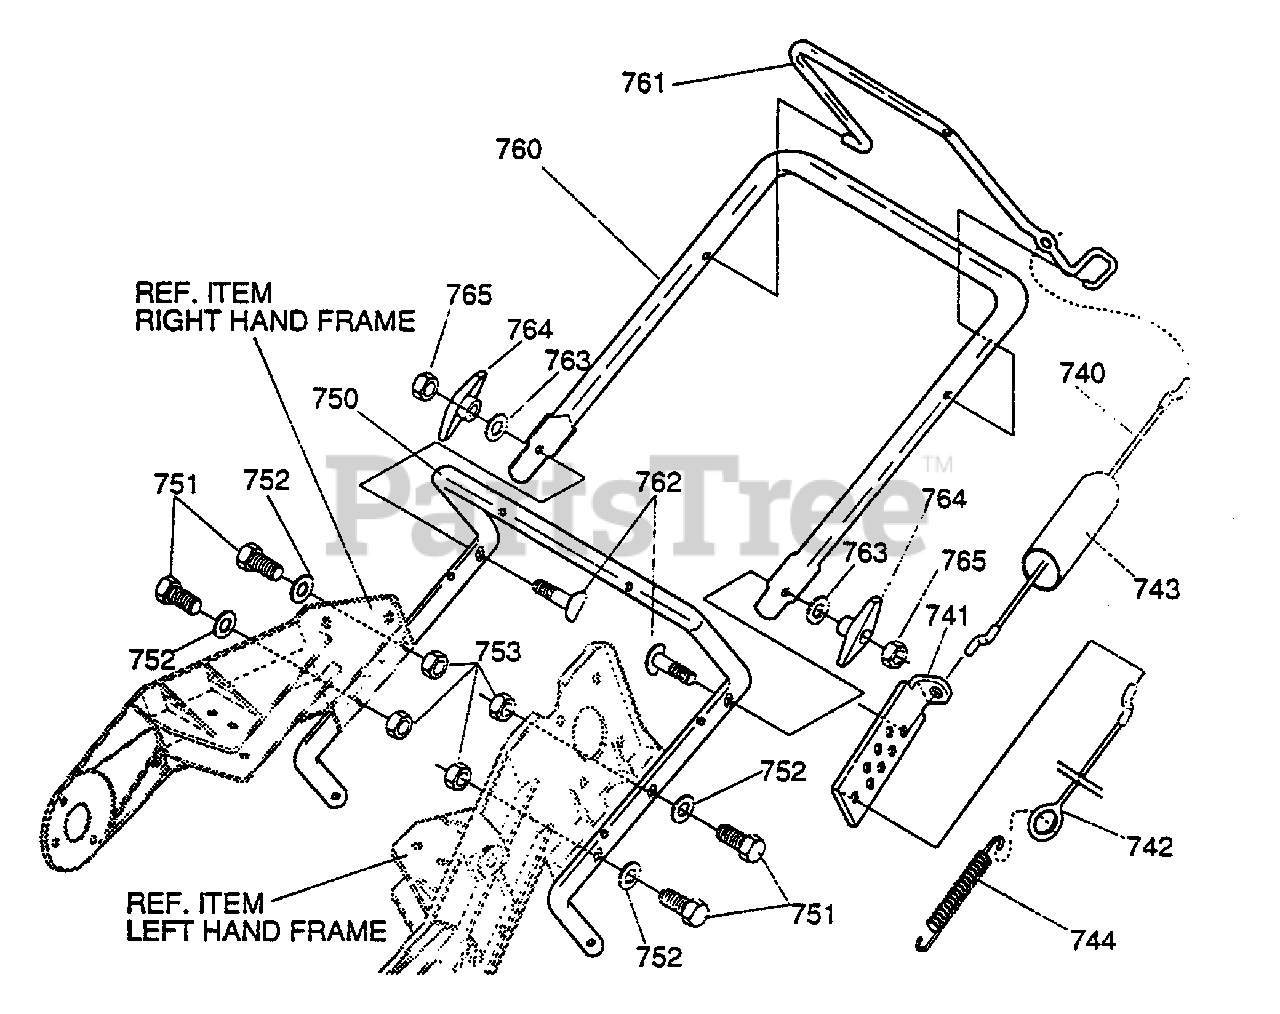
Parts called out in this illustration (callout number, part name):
740	CABLE, UPPER CONTROL
741	BRACKET, CABLE ADJ
742	CABLE, LOWER CONTROL
743	BOOT, CLUTCH SPRING
744	SPRING, EXTERNAL
750	HANDLE, LOWER
751	SCREW, 1/4-20 X 1.25
752	FLATWASHER .281 X .63 X .065
753	NUT, 1/4-20 REG HEX CTRLK
760	HANDLE, UPPER
761	BAIL, CONTROL
762	BOLT, 5/16-18 X 1.75
763	WASHER, FORM .344 ID 1.0
764	KNOB, T W/NUT
765	NUT, 5/16-18 REG HEX
